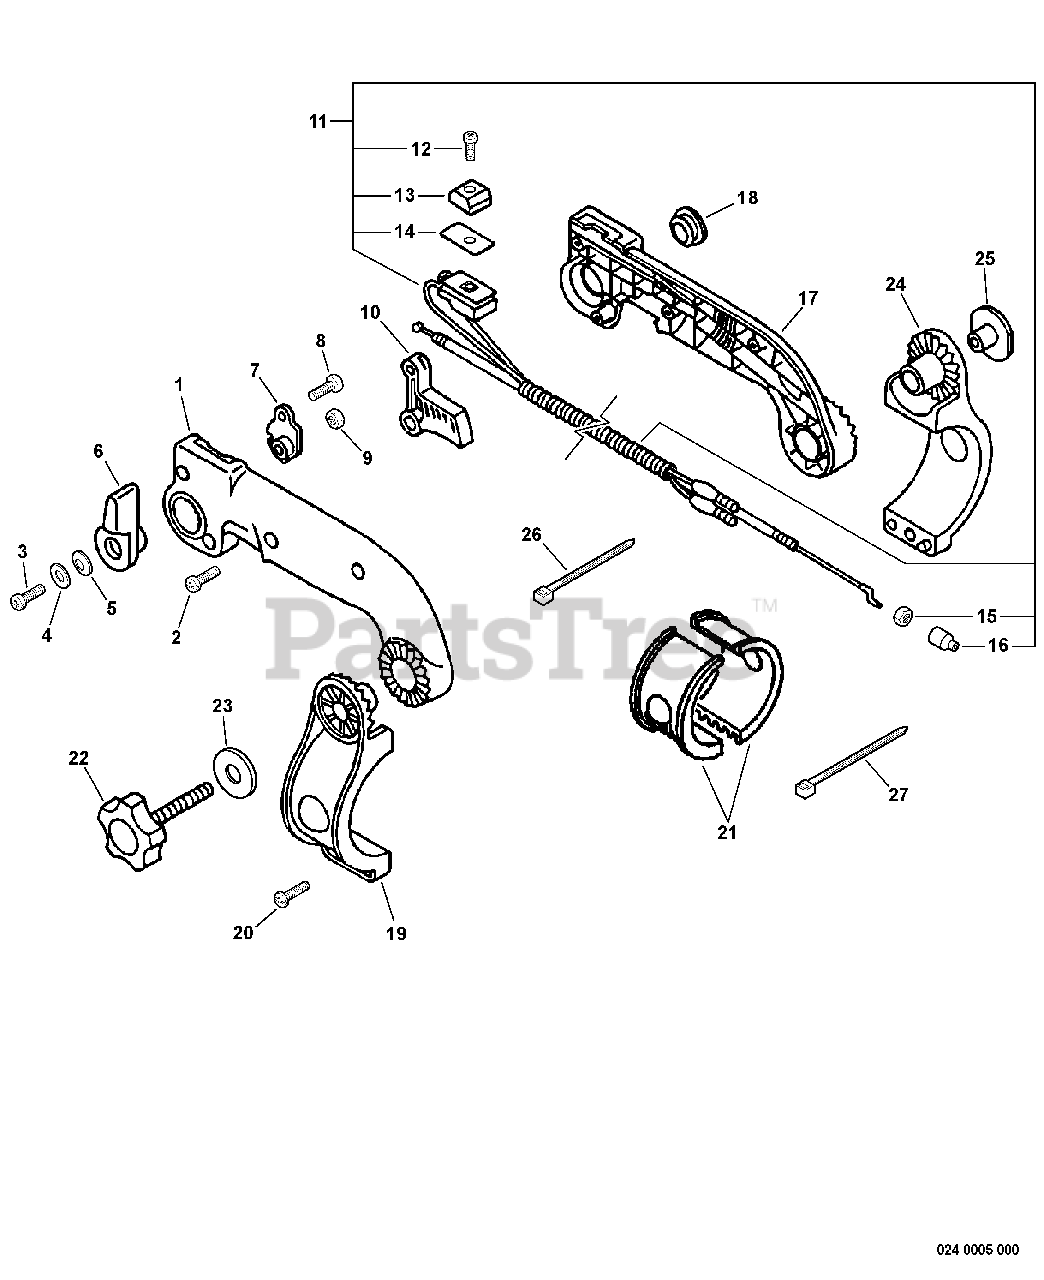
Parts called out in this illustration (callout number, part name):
1	HANDLE, CONTROL - LEFT
2	SCREW - 4X22
3	SCREW - 6X20
4	LOCKWASHER - 6
5	WASHER - 6
6	CONTROL, THROTTLE
7	BRACKET, THROTTLE
8	SCREW - 4X10
9	LOCKNUT - 6
10	TRIGGER, THROTTLE
11	CONTROL CABLE ASSY
12	SCREW - 3X10
13	KNOB, SWITCH - ORANGE
14	COVER, SWITCH - STOP
15	LOCKNUT - 6
16	CAP, DUST
17	HANDLE, CONTROL - RIGHT
19	BRACKET, HANDLE - LEFT
20	SCREW - 5X20 -- TAPPING
22	THUMBSCREW
23	WASHER - 6
24	BRACKET, HANDLE - RIGHT
26	TIE, CABLE - SMALL
27	TIE, CABLE - LARGE
